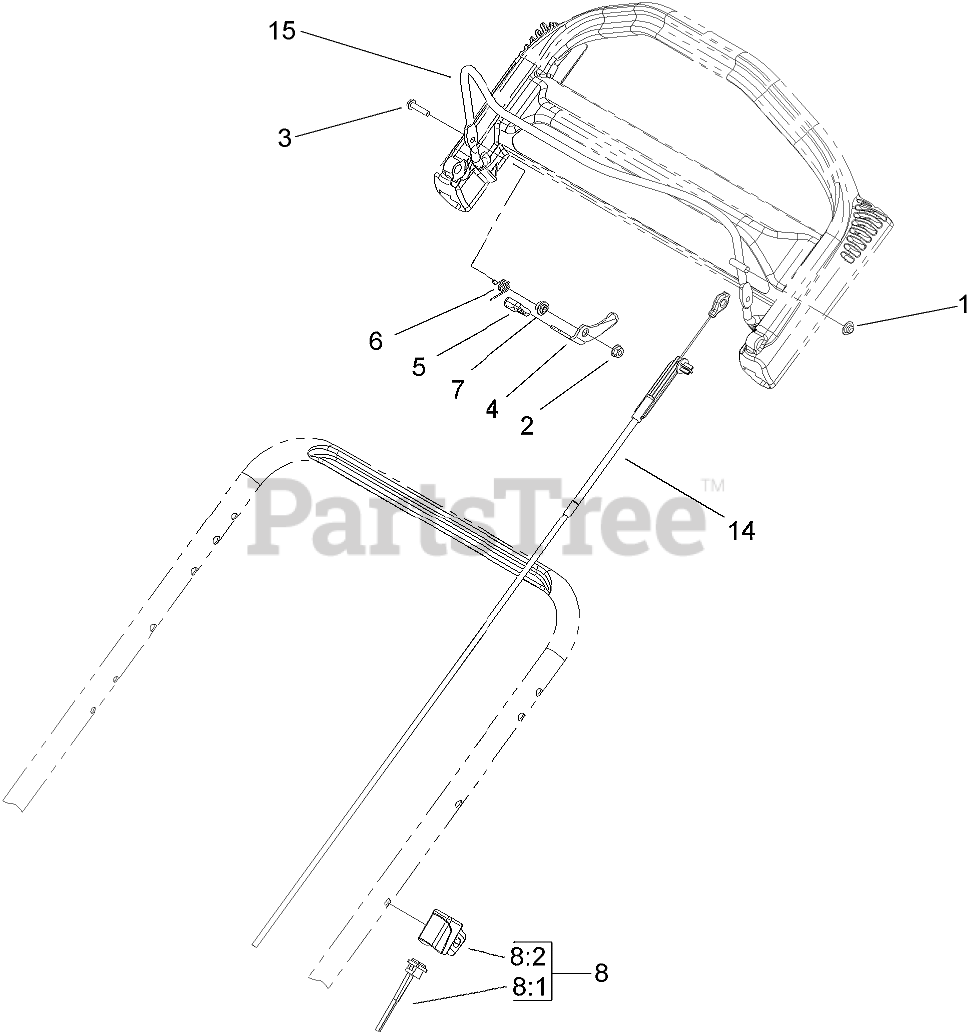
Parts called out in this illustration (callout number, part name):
1	NUT-SPEED
2	NUT-LOCK, FLANGE
3	SCREW-HWH
4	LEVER
6	SPRING-TORSION
7	SPACER
8	BBC SWITCH ASM
8:1	HARNESS-WIRE
8:2	HOUSING-SWITCH, BBC
14	CABLE ASM
15	BAIL-BRAKE
